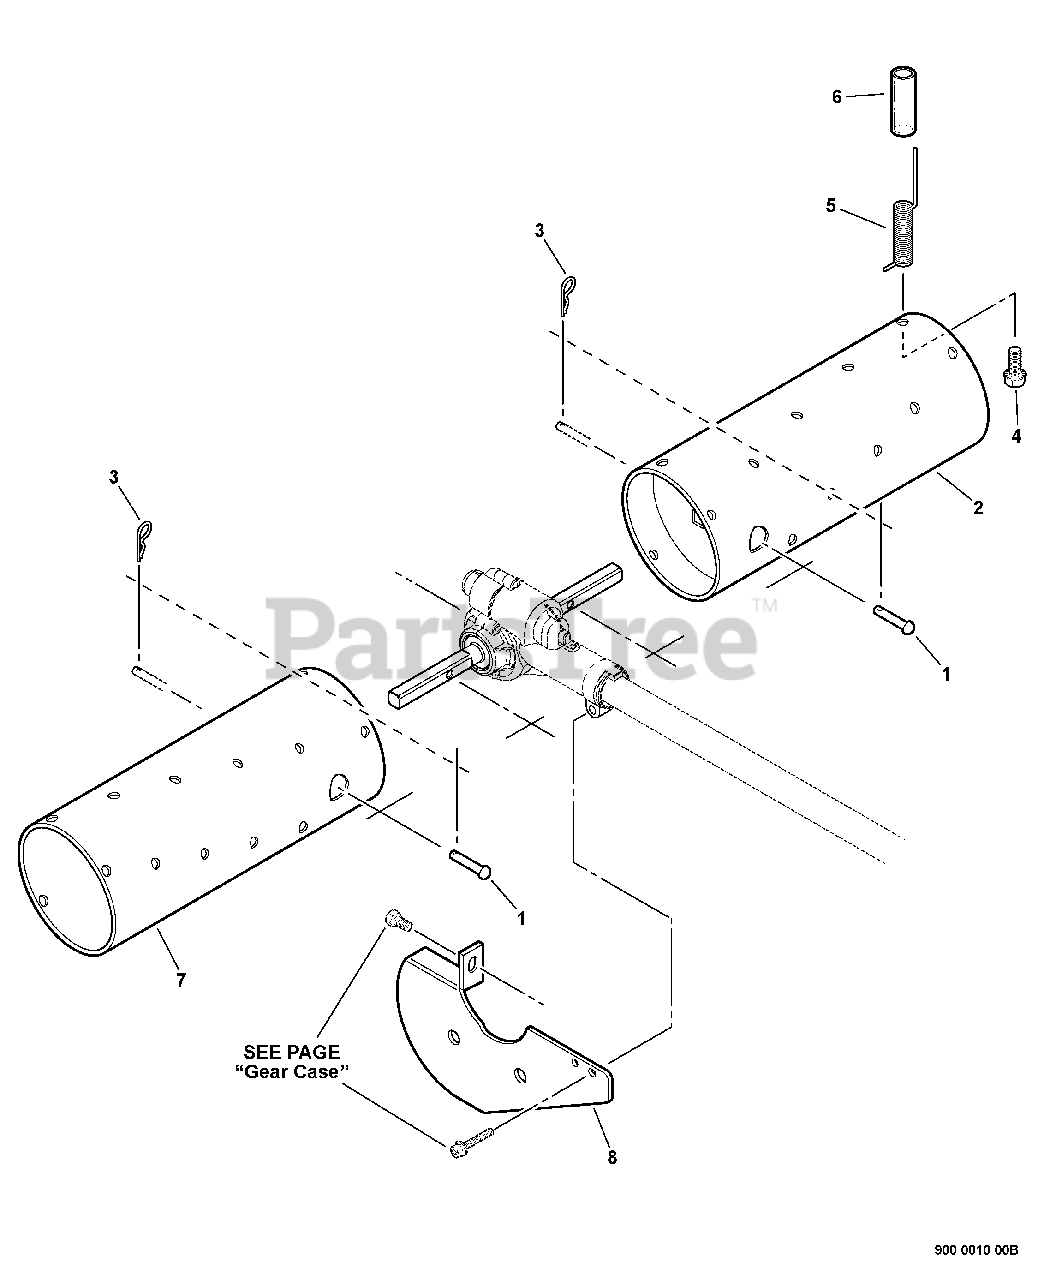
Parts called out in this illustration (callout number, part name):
1	PIN, CLEVIS
2	DRUM - RIGHT
3	PIN, COTTER 5
5	SPRING, TORSION
6	TUBE, FLEXIBLE
7	DRUM - LEFT
8	GUIDE, GRASS
